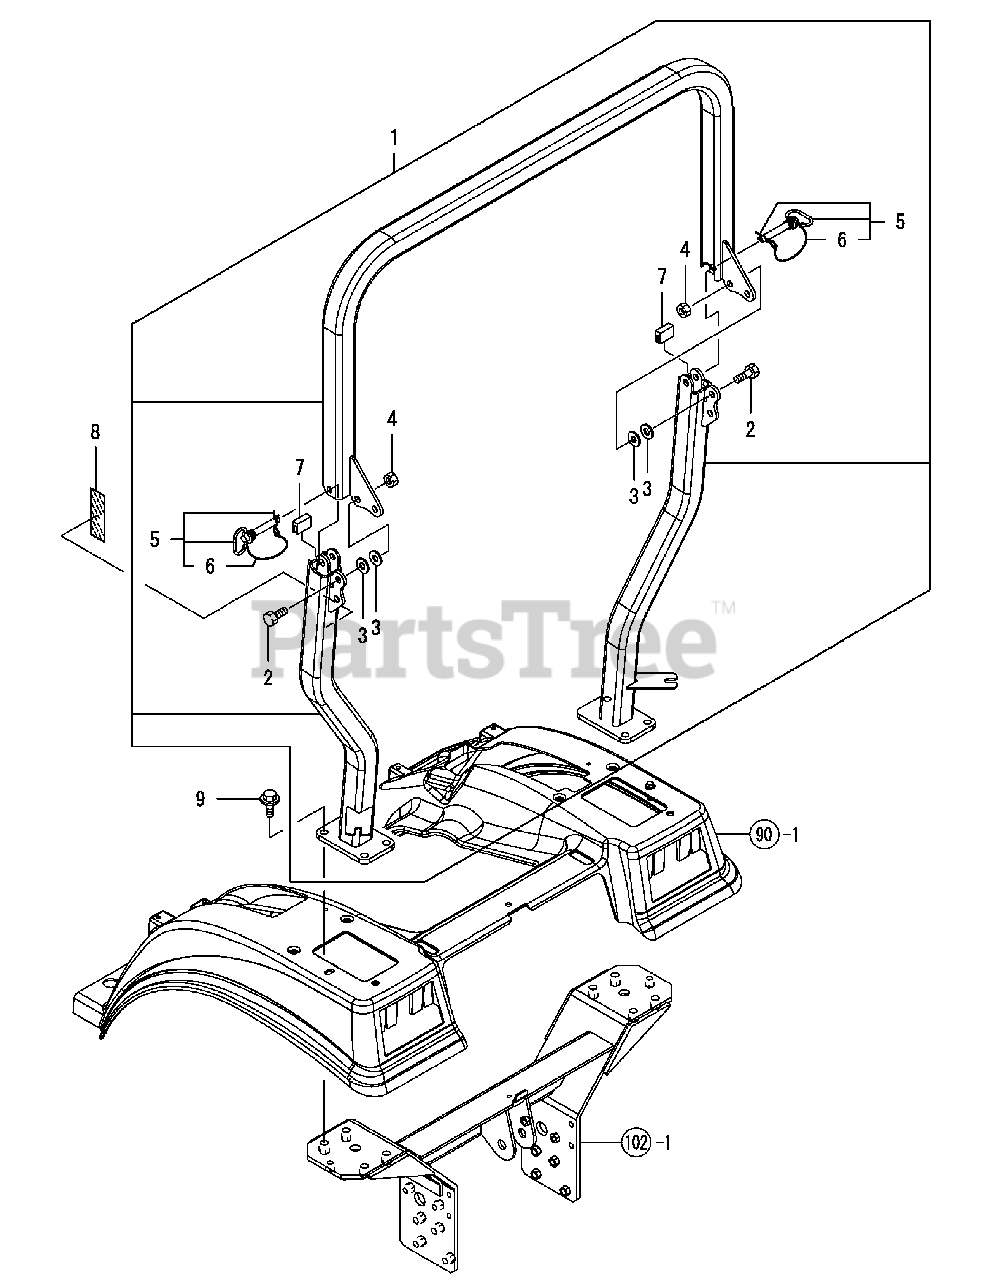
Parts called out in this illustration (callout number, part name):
1	ROPS M ASSY, TLB
2	BOLT 1/2-13X1.25
7	RUBBER, CUSHION
8	LABEL, WARNING ROPS
9	BOLT M12X 35 PLATED
